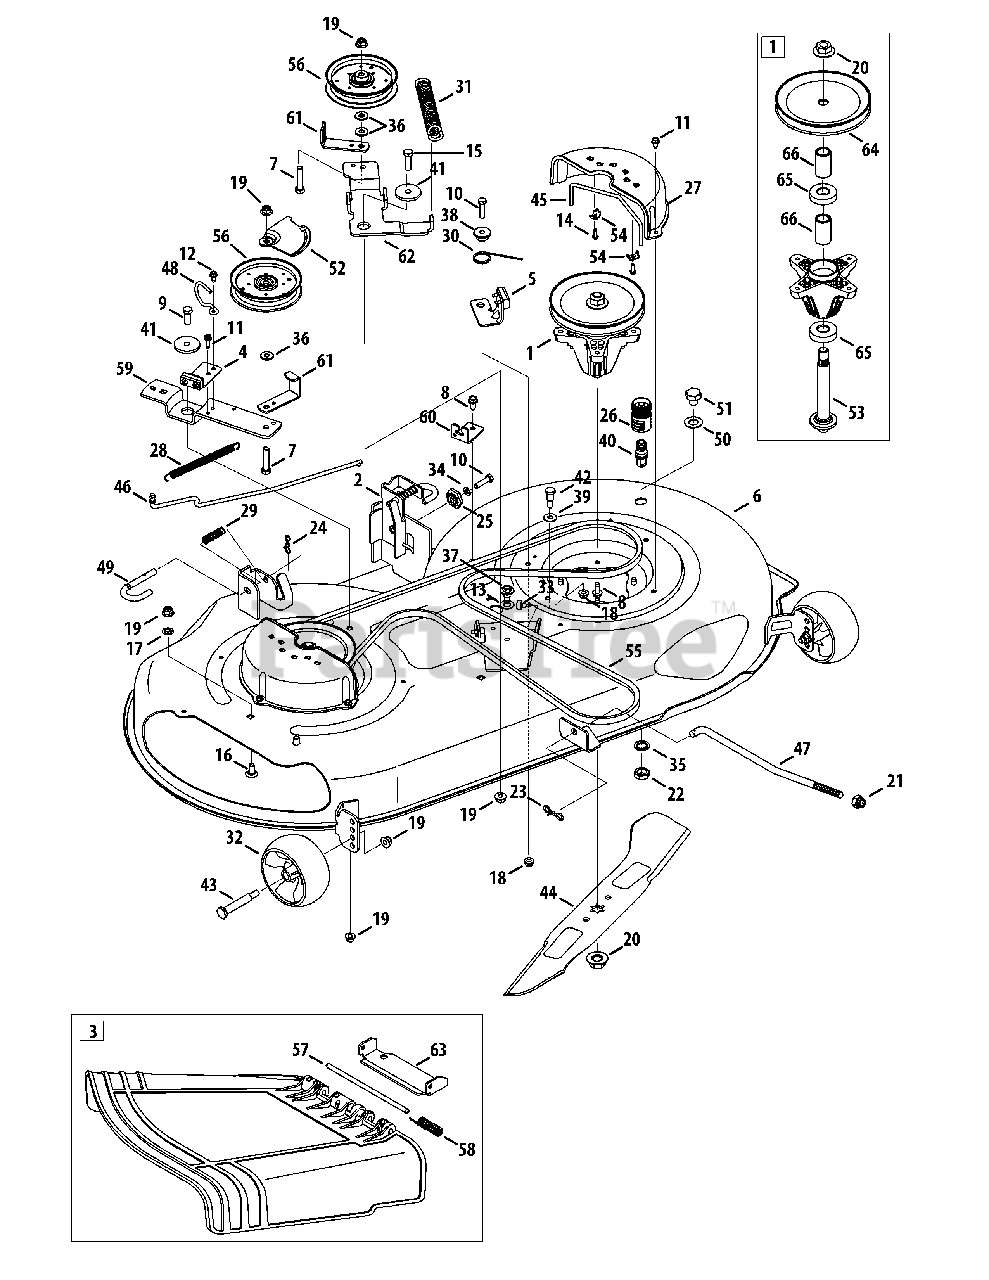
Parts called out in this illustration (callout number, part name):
1	Spindle Assembly, Pulley 6.93 Dia
2	Bracket Assembly, Deck Hanger, LH
3	Chute Deflector Assembly
4	Brake Assembly, Deck, 42/46
5	Brake Assembly, Deck, 46"
6	Deck Assembly
7	Hex Screw, 3/8-16 x 2.00
8	Screw, Self-tapping, 5/16-18, .750
9	Hex Screw, 3/8-16, 1.00, Gr5, Std
10	Hex Screw, 5/16-18, 1.25, Gr5, Std
11	Screw, Self-tapping, 1/4-20, 0.500
12	Screw, Self-tapping, 1/4-20, .750
13	Washer, Flat, .474 x .879 x .064
14	Screw, B, #10-16, 0.625
15	Hex Screw, 3/8-16 x 1.25
16	Bolt, Carriage, 3/8-16, 0.75, Gr1
17	Nut, Push, 3/8
18	Nut, Flange Lock, 5/16-18, Nylon
19	Nut, Flange Lock, 3/8-16, Nylon
20	Nut, Flange, 5/8-18
21	Nut, Lock, 1/2-13
22	Nut, Hex, M16-1.5
23	Bow-Tie Cotter Pin
24	Bow-Tie Cotter Pin, 72
25	Gear, Deck Adjustment
26	Water Nozzle Adapter
27	Belt Cover, Universal
28	Spring, Extension, .62 x 6.12
29	Spring, Compression, .535 x 1.751
30	Spring, Torsion, .992 I.D X 1.17 O.D
31	Spring, Extension, 1.05 X 6.346
32	Wheel, Deck, 5.0 Dia Ball
33	Bumper, .62 Dia X .3
34	Washer, Lock, 5/16, Regular Duty
35	Washer, Lock, 5/8, Int Tooth
36	Washer, Flat, .385 x .870 x .092
37	Shoulder Spacer, .43 x .29, 5/16-18
38	Shoulder Spacer, .50 x .145
39	Washer, Flat, .343 X .880 X .062
40	Deck Water Nozzle
41	Shoulder Spacer, .8840 X .190
42	Shoulder Screw, .437 Dia. X .54
43	Bolt, Shoulder, .496 x 2.50, 3/8-16
44	Blade, Cut, 23.25" 2-In-1
45	Rod, Keeper, Belt
46	Rod, Control, Brake 46"
47	Rod, Lift, Deck, Medium
48	Rod, Keeper, Belt
49	Rod, Deck Release
50	Washer, Flat, .64 X 1.24 X .06
51	Plug, Bolt, M16 X 1.5
52	Belt Guide
53	Spindle Shaft, 6.05 LG.
54	Clamp, Casing
55	Belt, V-Typ, A Sec
56	Pulley, Idler, 4.25"Dia
57	Hinge Pin
58	Torsion Spring
59	Bracket, Idler, Pivot, 46
60	Bracket, Cable, Deck Engagement
61	Bracket, Guard, Belt, 4.25 Pulley
62	Bracket, Idler, 46" Lh
63	Chute Bracket
64	Deck Pulley, 6.93 DIA
65	Ball Bearing, .787ID X 1.85 ODX.551
66	Spacer, .792 X 1.060 X 1.860 LG
